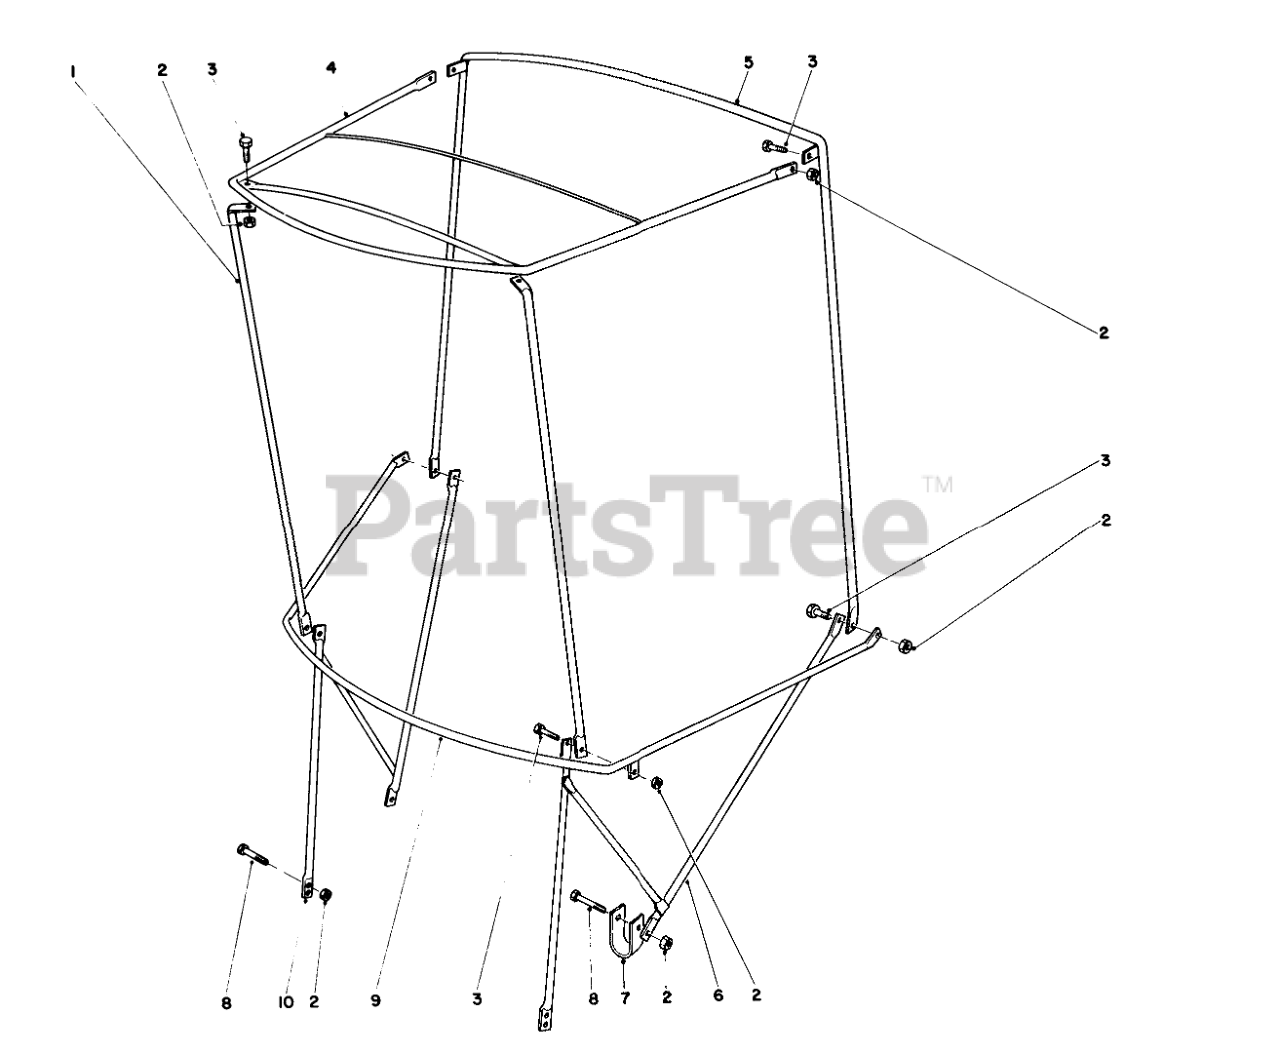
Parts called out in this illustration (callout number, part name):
2	NUT-HEX, SIDE DEFORM
3	SCREW-HH
4	FRAME-TOP
5	BOW-VERTICAL, REAR
6	ATTACHING BRKT L
7	U CLAMP
8	SCREW-HH
9	BOW-CURVED
10	ATTACHING BRKT R
